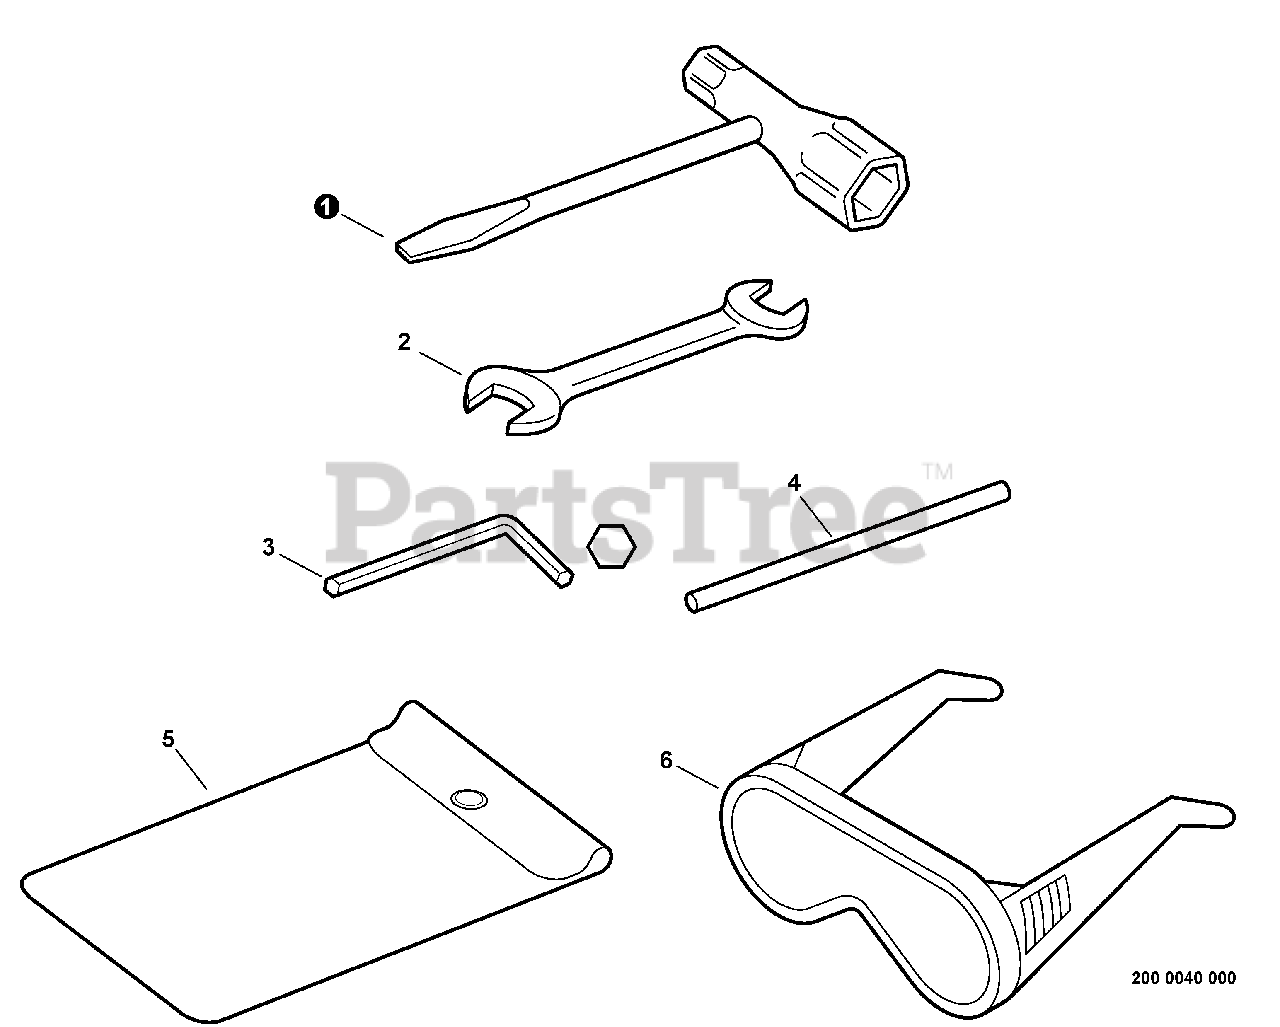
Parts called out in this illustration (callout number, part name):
1	T-WRENCH - 17X19mm
2	SPANNER - 8X10mm
3	HEX KEY - 4mm
4	ROD, LOCKING - 5X120mm
5	BAG, TOOL
6	GOGGLES
